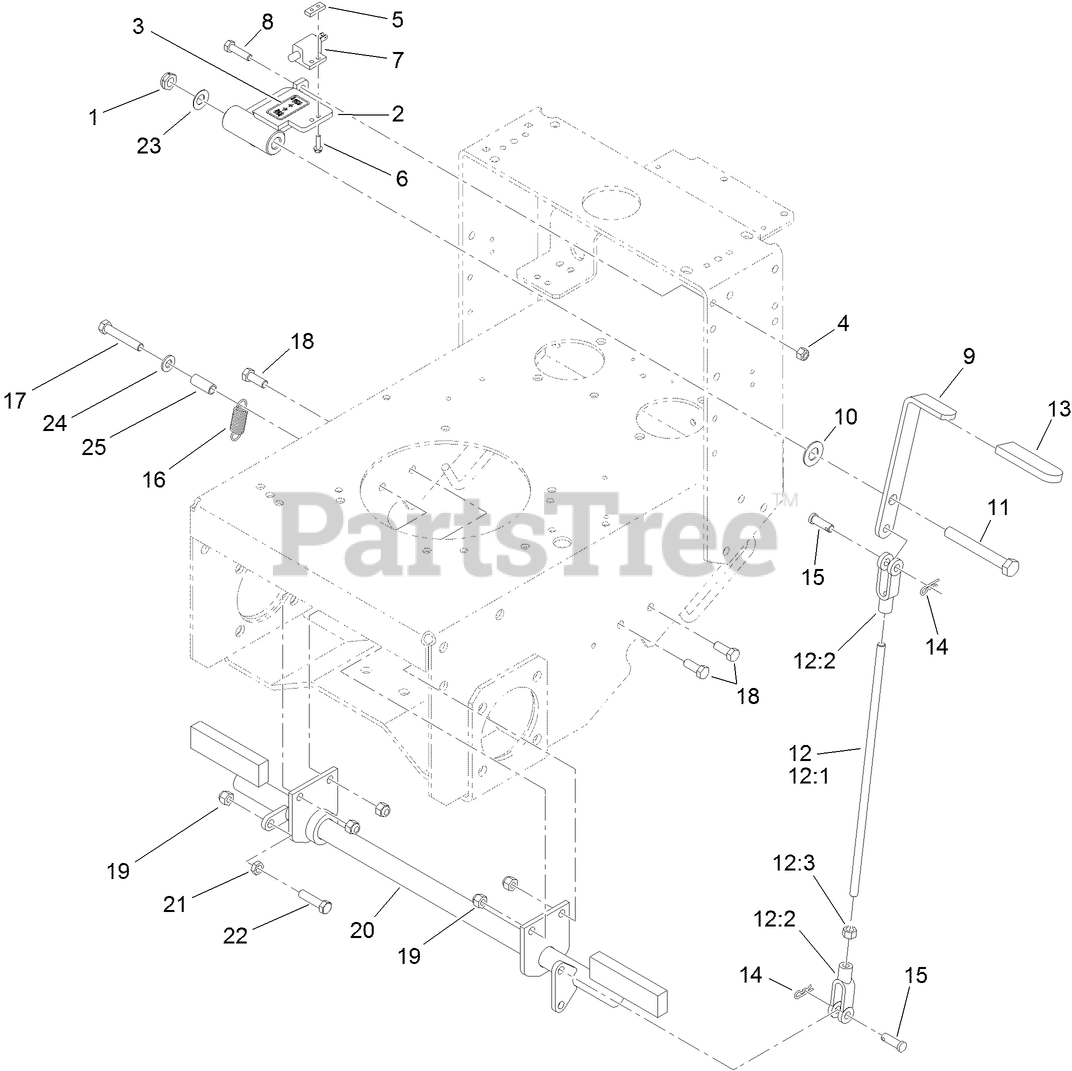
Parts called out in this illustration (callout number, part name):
1	NUT-LOCK, NI
2	SUPPORT-HANDLE
3	DECAL-BRAKE
4	NUT-LOCK, NI
5	PLATE-TAPPED
6	SCREW-HWH
7	SWITCH-CLOSED, NORMALLY
8	SCREW-HH
9	HANDLE-BRAKE
10	BEARING-THRUST
11	SCREW-HH
12	BRAKE ROD ASM
12:1	ROD-BRAKE
12:2	YOKE-LINKAGE, BRAKE
12:3	NUT-HEX
13	GRIP-LEVER
14	PIN-COTTER
15	PIN-CLEVIS
16	SPRING-BRAKE
17	SCREW-HH
18	SCREW-HH
19	NUT-LOCK, NI
20	SHAFT-BRAKE, PARKING
21	NUT-JAM
22	SCREW-HH
23	WASHER-SPRING, CONICAL
24	WASHER-FLAT
25	SPACER-SPRING
